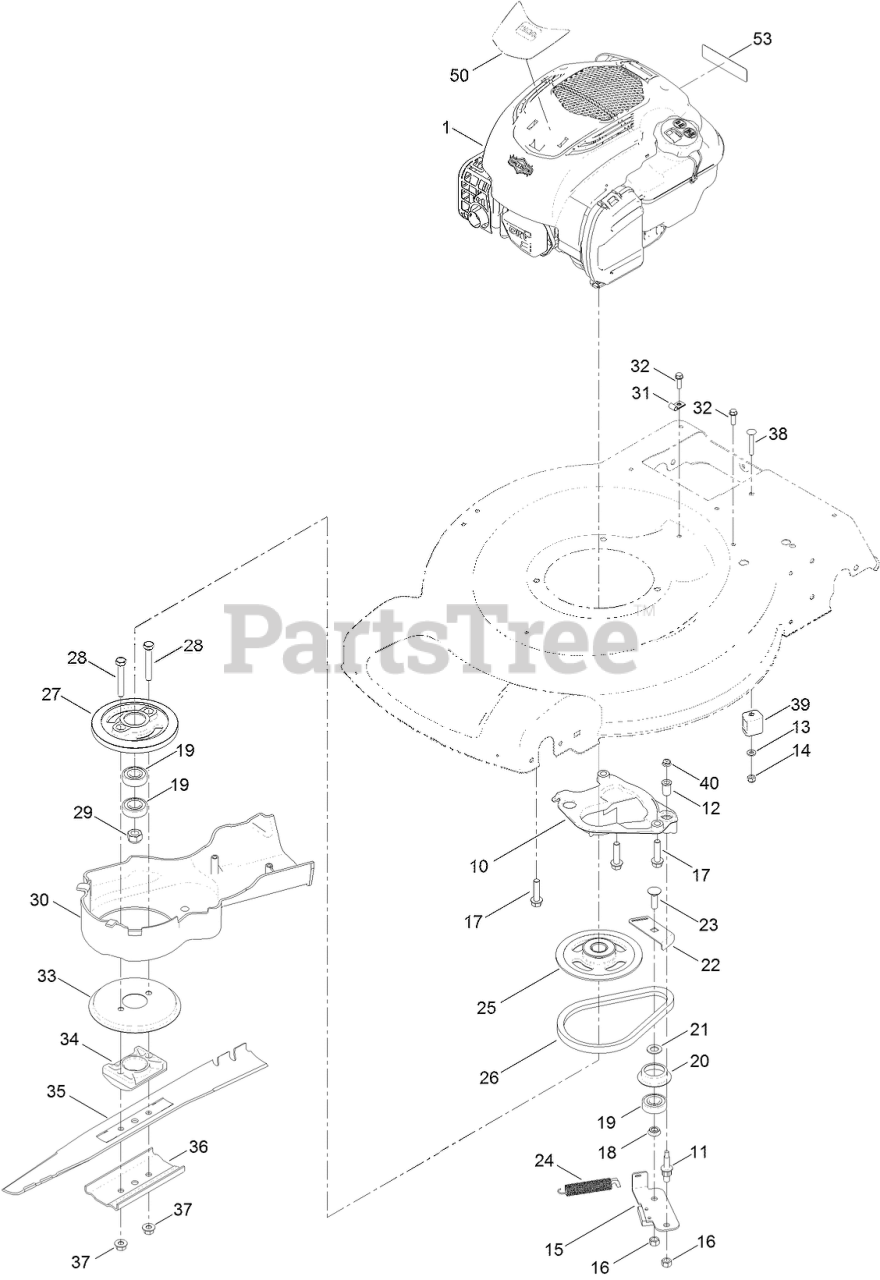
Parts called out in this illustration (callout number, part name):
10	PLATE-ANCHOR
11	BOLT-SHOULDER
12	BUSHING
13	WASHER-FLAT
14	NUT-LOCK, NI
15	PLATE-BRAKE
16	NUT-HEX
17	SCREW-HWH
18	SPACER-BEARING
19	BEARING-BALL
20	RETAINER-BELT
21	SPACER
22	PLATE-GUIDE
23	BOLT-CARR
24	SPRING-TENSION, BRAKE
25	PULLEY
26	BELT
28	SCREW-HH
29	NUT-HEX
31	CLIP-CLOSED, INSULATED
32	SCREW-HWH
33	DISC
34	SUPPORT-BLADE
35	BLADE-22 INCH
36	SUPPORT-BLADE
37	NUT-FLANGE, LOCK
38	SCREW-CARR
39	ANCHOR-CABLE
40	NUT-HF
50	DECAL-SHROUD
53	DECAL-ARRESTER, SPARK
